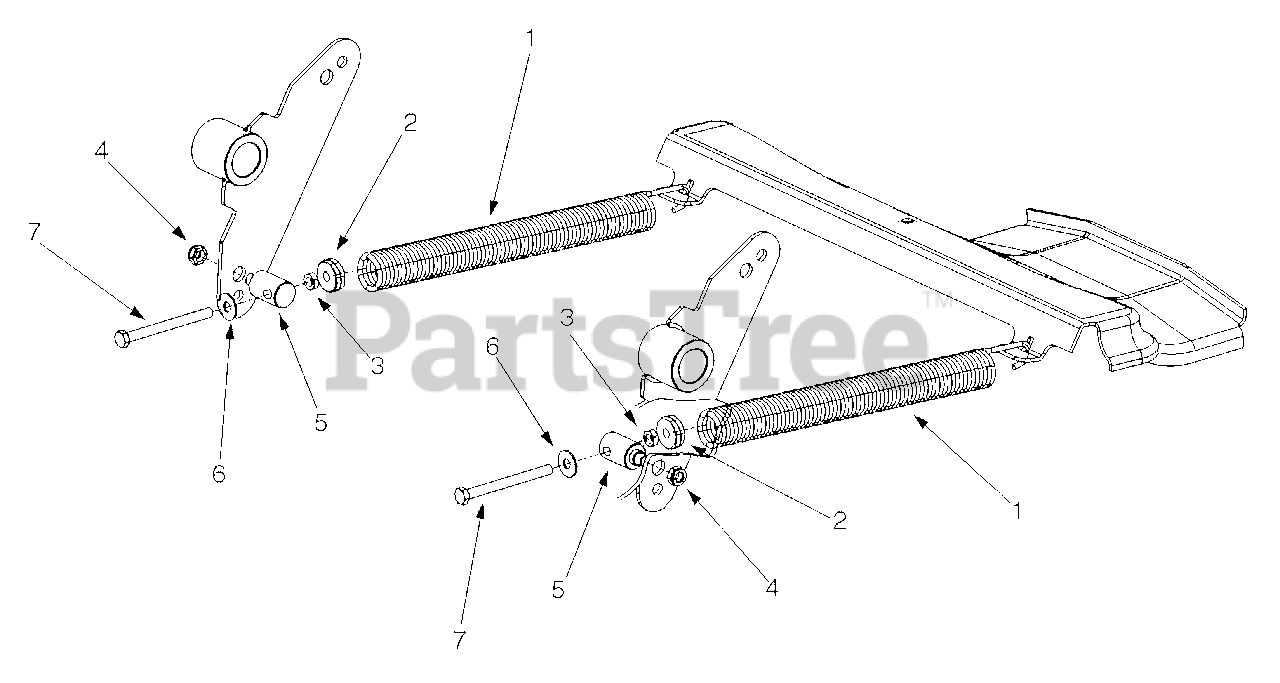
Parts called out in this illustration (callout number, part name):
1	Extension Spring 1.25 OD x 11.5 Lg
2	Spring
3	Hex Jam Nut 5/16-18
4	Jam Lock Nut 3/8-24
5	Ferrule
6	Washer 5/16
7	Hex Cap Screw 5/16-18 x 3.50
